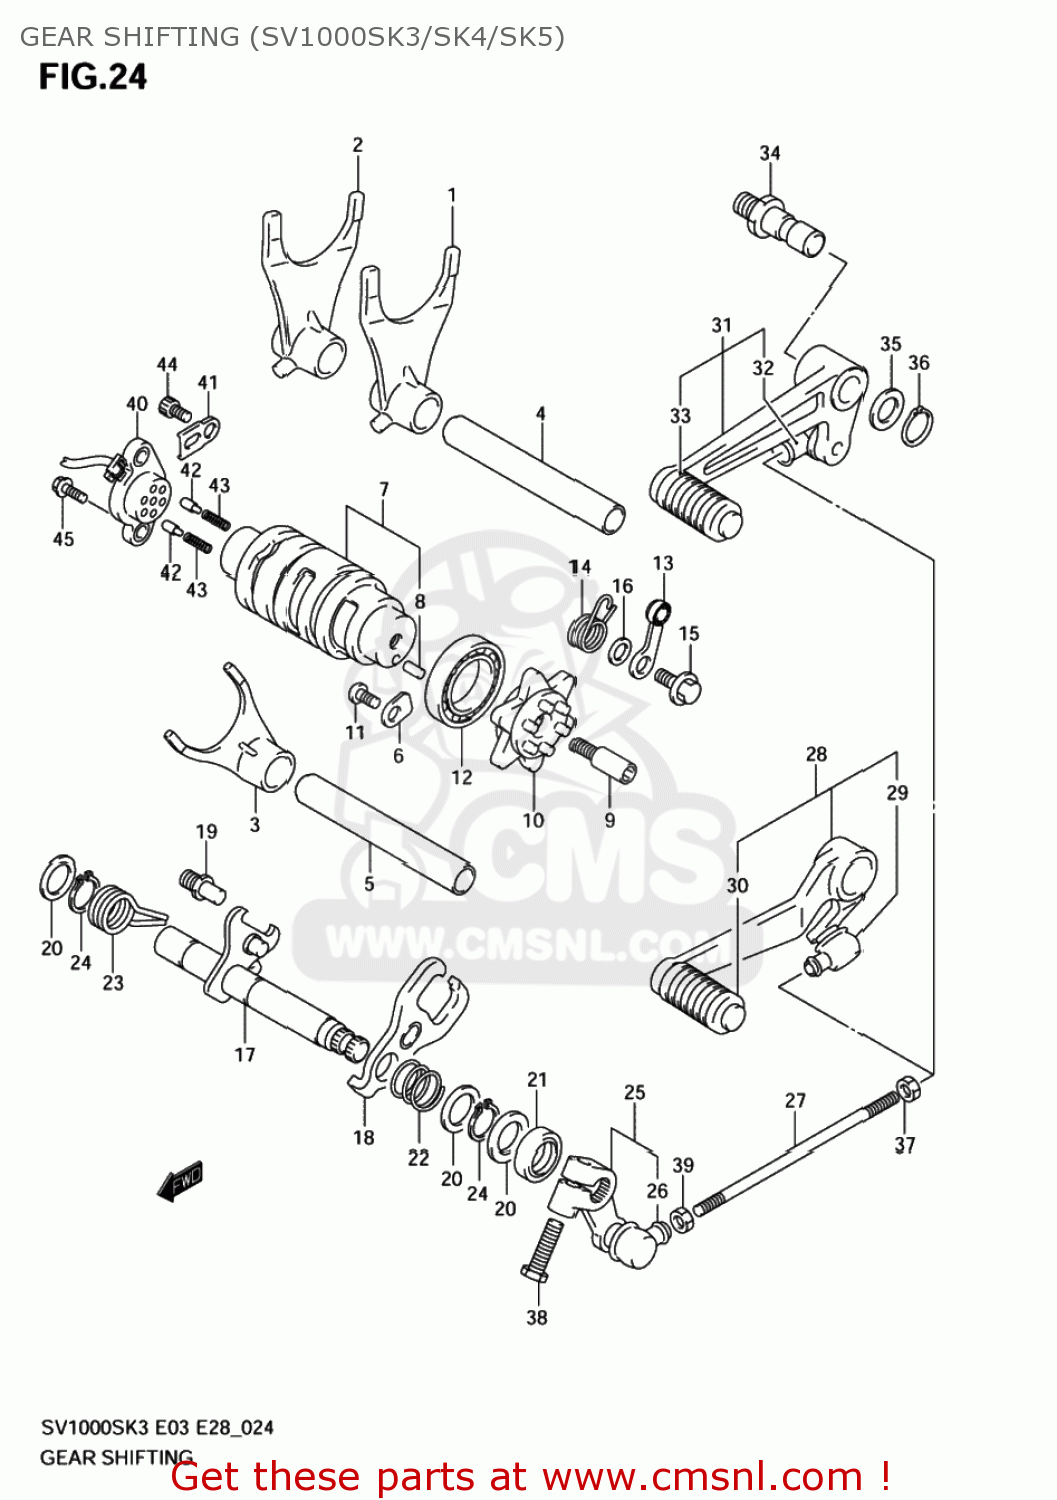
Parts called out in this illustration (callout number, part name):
1	FORK,GEAR SHIFT
2	FORK,GEAR SHIFT NO.1
3	FORK,GEAR SHIFT NO.3
4	SHAFT,GEAR SHIFT FORK
5	SHAFT,GEAR SHIFT FORK
6	RETAINER
7	CAM,GEAR SHIFT
8	PIN
9	PIN,SHIFT CAM DRIVEN GEAR
10	PLATE,GEAR SHIFT CAM
11	BOLT(6X12)
12	BEARING
13	STOPPER,SHIFT CAM
14	SPRING,GEAR SHIFT CAM STOPPER
15	BOLT(6X14.3)
16	WASHER
17	SHAFT,GEAR SHI
18	PLATE,GEAR SHIFT CAM DRIVE
19	STOPPER,GEAR SHIFT ARM
20	SHIM(14X22X1)
21	SEAL,OIL(14X22X6)
22	SPRING
23	SPRING
24	CIRCLIP
25	ARM,GEAR SHIFT LINK
26	COVER,DUST
27	ROD,GEAR SHIFT LINK
28	LEVER ASSY,GEAR SHIFT
29	COVER,DUST
30	RUBBER,GEAR SHIFT PEDAL
31	LEVER ASSY,GEAR SHIFT
32	COVER,DUST
33	RUBBER,GEAR SHIFT PEDAL
34	SHAFT,GEAR SHIFT LEVER
35	WASHER(12.5X20X1)
36	CIRCLIP,12 MM
37	NUT
38	BOLT
39	NUT
40	BASE ASSY,GEAR SHIFT TERMINAL
41	CLAMP,GENERATOR LEAD WIRE
42	PIN(5X15.5)
43	SPRING
44	BOLT
45	BOLT
